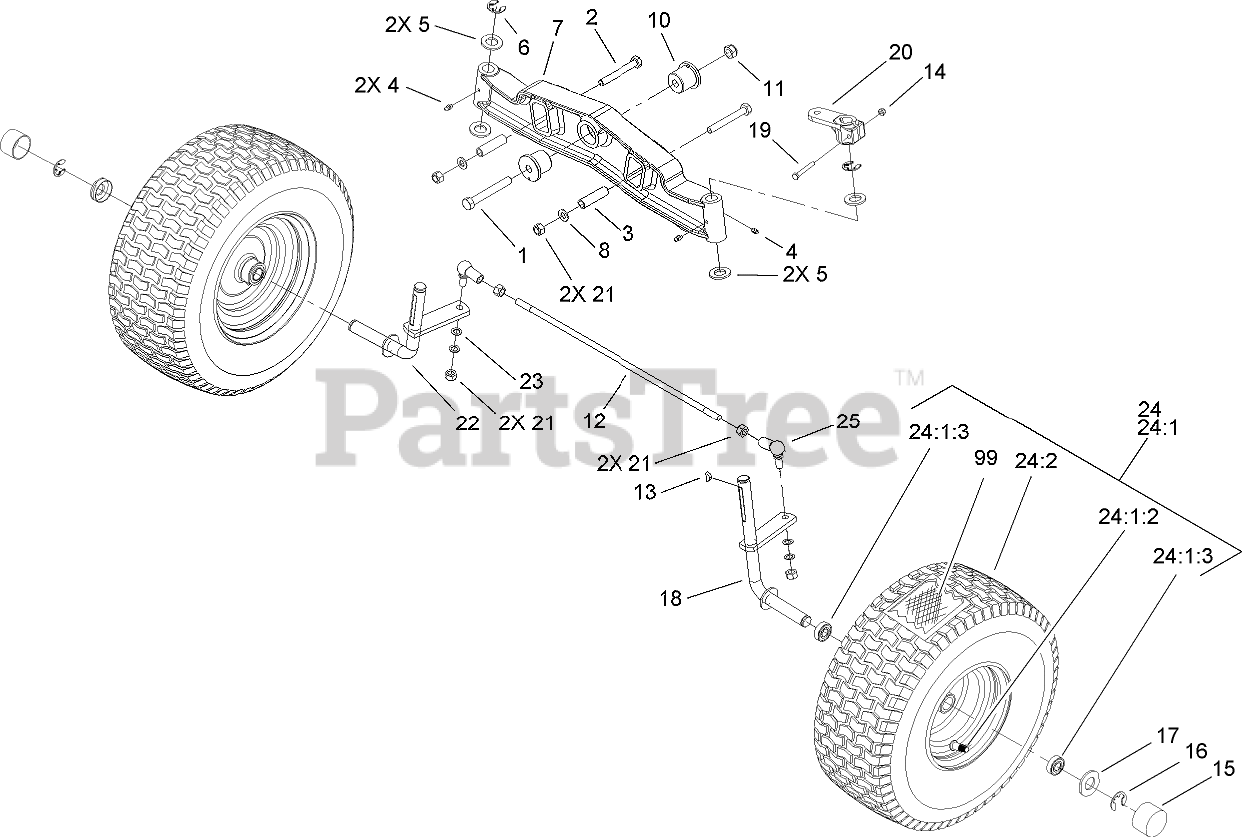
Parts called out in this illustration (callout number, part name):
1	SCREW-HH
2	SCREW-HH
3	SPACER
4	FITTING-GREASE
5	WASHER-FLAT
6	CLIP-SPRING
7	AXLE-FRONT
8	WASHER-FLAT
10	BUSHING-AXLE, FRONT
11	NUT-LOCKING, SELF
12	ROD-TIE, FRONT AXLE
13	KEY-WOODRUFF
14	NUT-LOCK
15	CAP-HUB
16	CLIP-SPRING
17	RETAINER-CAP, HUB
18	SPINDLE-LH
19	SCREW-HH
20	LEVER-SPINDLE, STEERING
21	NUT-LOCK, NI
22	RH SPINDLE ASM
23	Washer
24	WHEEL AND TIRE ASM
24:1	WHEEL ASM
24:1:2	Valve-Tire
24:1:3	BEARING-WHEEL
25	JOINT-BALL, ANGLE
99	TUBE-INNER
